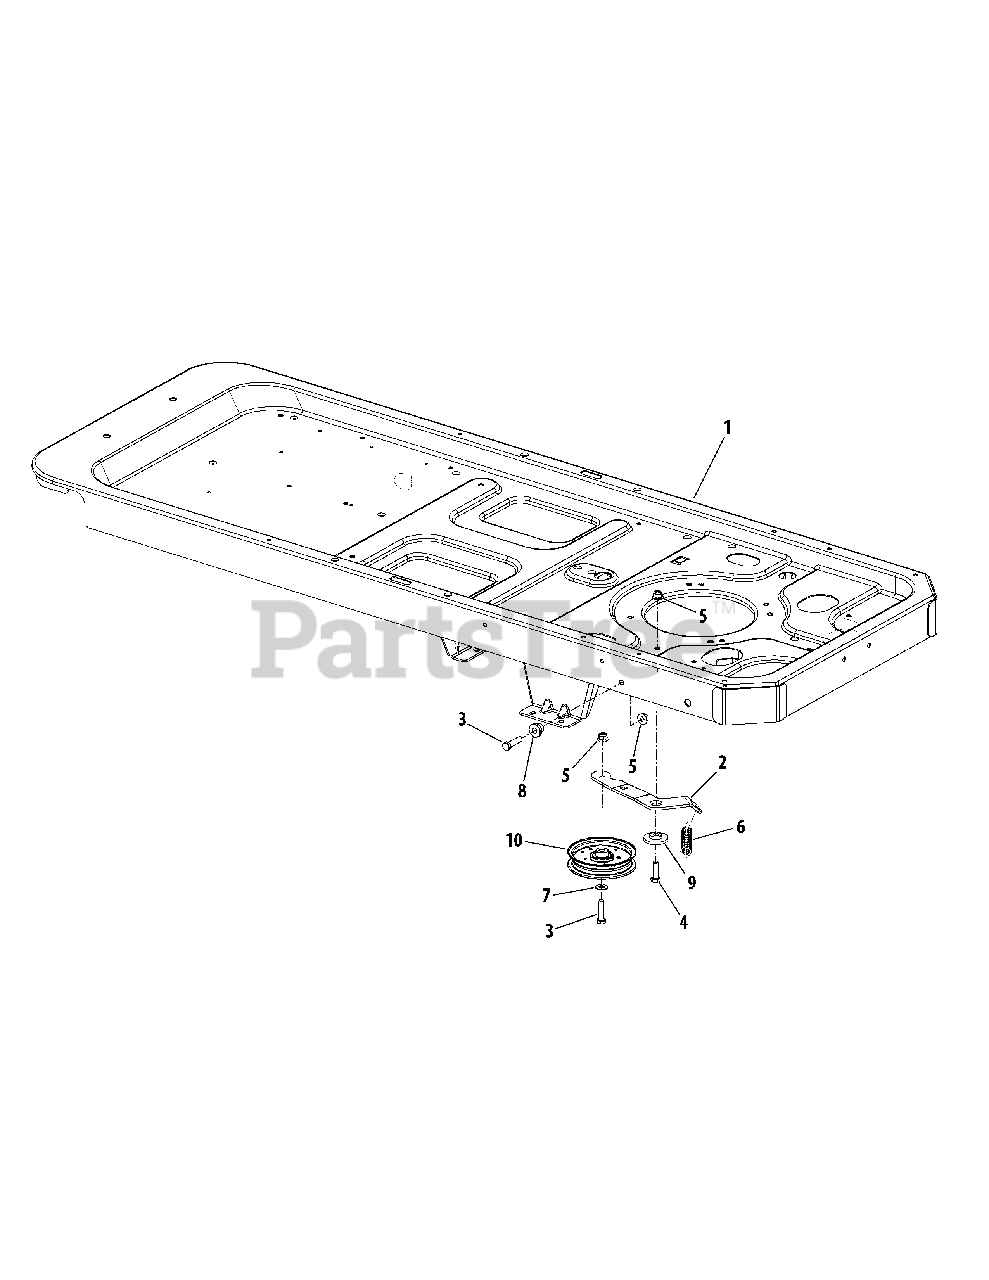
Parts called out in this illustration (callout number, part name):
3	Screw, Hex Cap, 3/8-16 x 1.5 Gr5
4	Screw, Hex Cap, 3/8-16 x 1.25 Gr5
5	Nut, Hex Flange Lock, 3/8-16 GrF
6	Spring, Extension, .75 x 5.06
7	Washer, Flat, .406 x .875 x.059
8	Spacer, Shoulder, .38 x 1.0 x .7
9	Spacer, Shoulder, .884 x 1.9
10	Pulley, Idler, 4.25" Dia.
